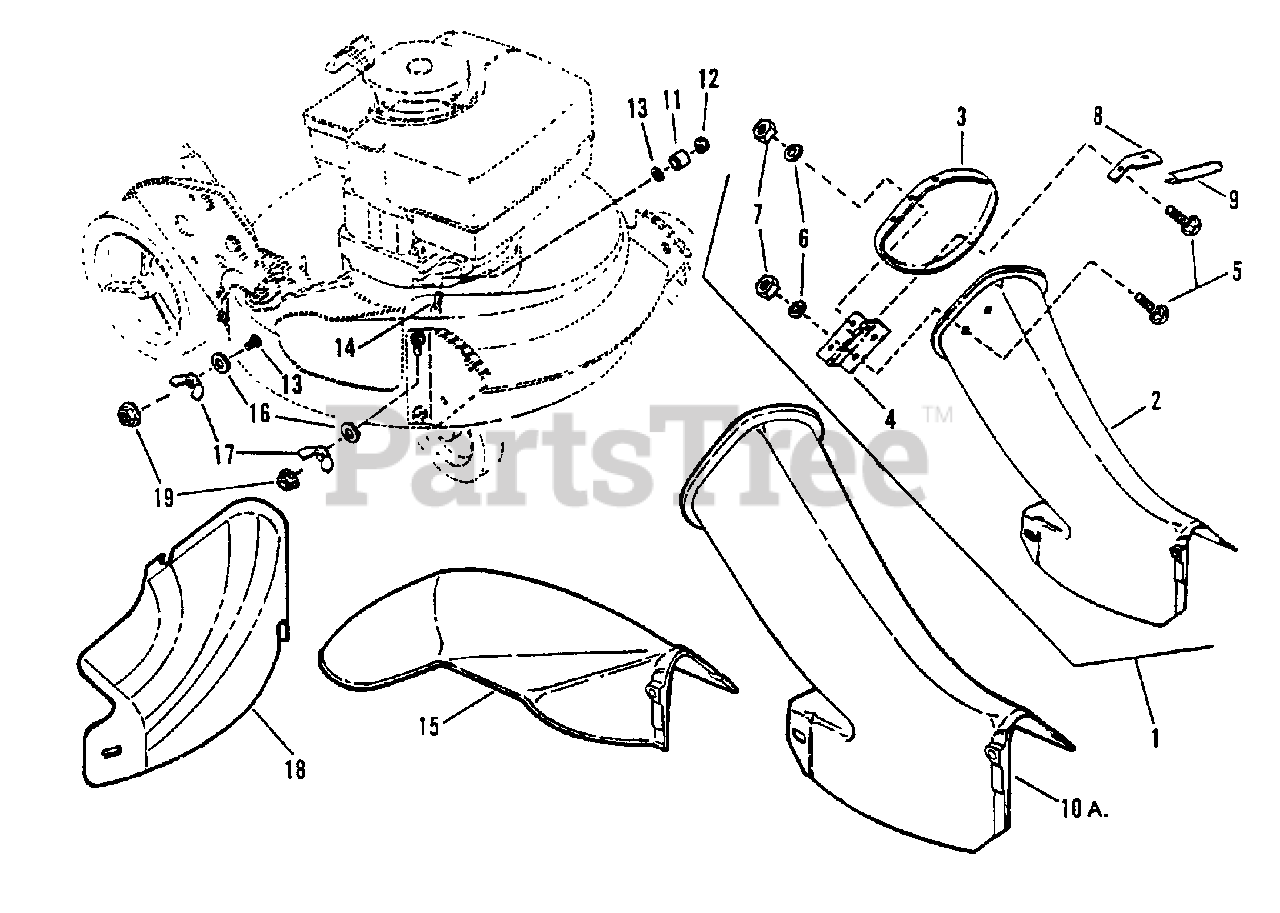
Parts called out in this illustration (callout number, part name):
1	ASSEMBLY, Bag Adapter & Cover
2	ADAPTER, Grass Bag
3	COVER, Bag Adapter
4	HINGE, Chute Cover
5	BOLT, 1/4-20 x 1/2" Short Neck Carriage, Grade 5
6	WASHER, 1/4 Internal Tooth Lock
7	NUT, 1/4-20 Hex, Grade 5
8	STOP, Cover
9	MOLDING, Trim
10A	ADAPTER, Grass Bag
11	SPACER
12	NUT, 5/16-18 Hex Flange Center Lock
13	RETAINER, 5/16 Bolt
14	BOLT, 5/16-18 x 3/4" Short Neck Carriage, Grade 5
15	CHUTE, Side
16	WASHER, 3/8" Flat
17	WING-NUT, 5/16-18 Nyloc
18	COVER, 21" Deck
19	NUT, 5/16-18 Large Flange Center Lock
